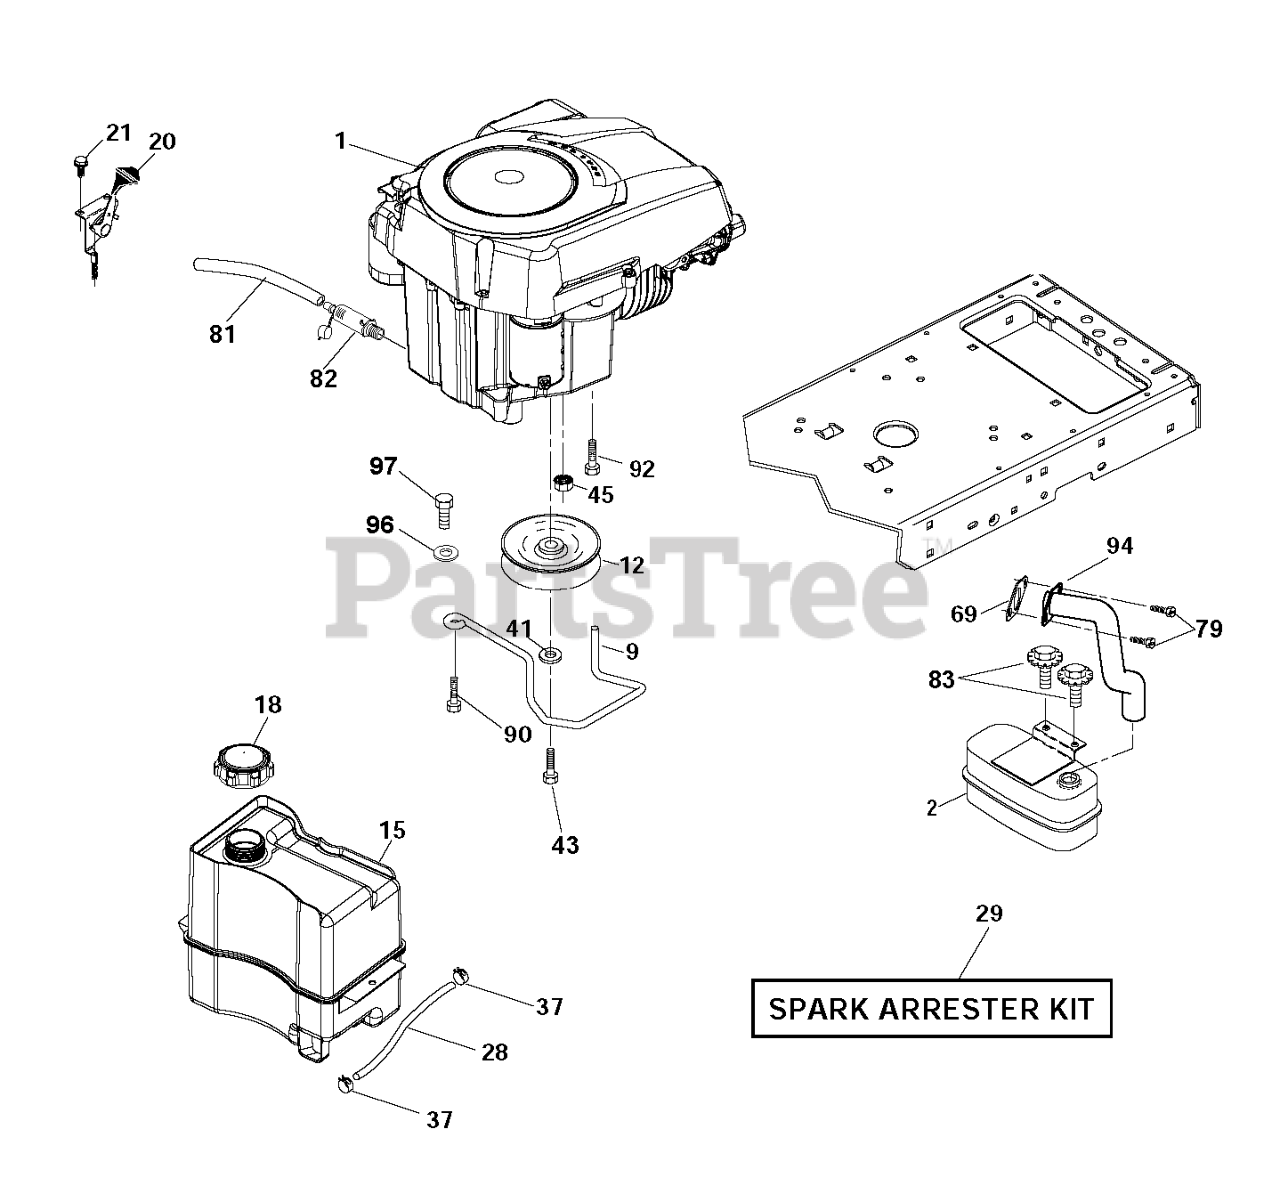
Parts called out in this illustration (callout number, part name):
2	MUFFLER.SINGLE.CYL.KOHL/B&S
9	KEEPER.BELT.ENGINE.3.25 (3 2)
12	PULLEY ENGINE
15	RP TANK FUEL FRT 1.5 GAL
18	FUEL CAP
20	CONTROL.TH/CK.C.
21	SCREW.#10 X 0.750.BOS
28	LINE.FUEL.20
29	KIT.SPARK ARRESTOR 794945 B&S
37	HOSE CLAMP
41	LOCKWASHER
43	BOLT HEX 7/16-20X4-1/4"
45	NUT
69	GASKET.EXHAUST.KOHLER
79	SCREW.SOCKET HD.5/16-1
81	TUBE, DRAIN OIL ASM.
82	PLUG DRAIN OIL EASY
83	BOLT.5/16-18UNCX3/4 W/SEMS.BLK
90	SCREW 3/8-16X1
92	SCREW 3/8-16X1
94	RP.TUBE.EXHAUST.KOHL.COURAGE
97	SCREW HEXWSHR 1/4-20X3/4
